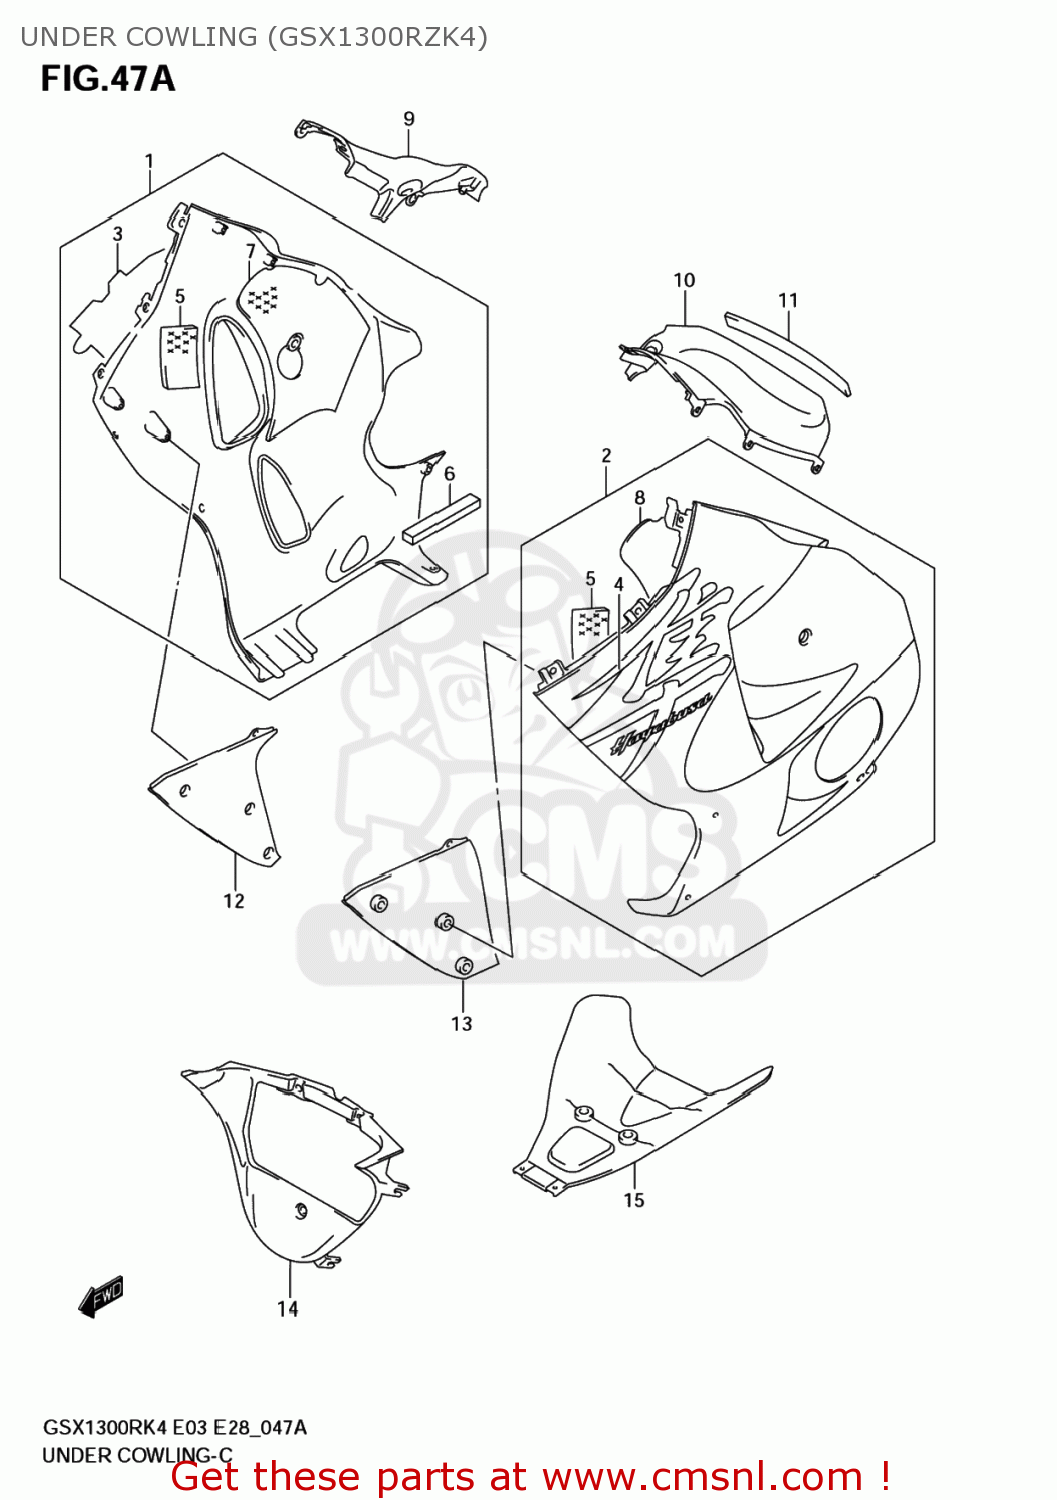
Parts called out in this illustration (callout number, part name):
1	COWL ASSY, UNDER RH (RED)
2	COWL ASSY, UNDER LH (RED)
3	EMBLEM,COWLING UNDER,R
4	EMBLEM,COWLING UNDER,L
5	CUSHION,UNDER COWLING NO,1
6	CUSHION,ENGINE COVER,RIGHT
7	CUSHION,UNDER COWLING NO.2,R
8	CUSHION,UNDER COWLING,L
9	PANEL,SIDE,R
10	PANEL,SIDE,L
11	MOLDING,SIDE PANEL
12	COWLING,UNDER INNER,R
13	COWLING,UNDER INNER,L
14	COWLING,UNDER CTR
15	COWLING,UNDER RR
